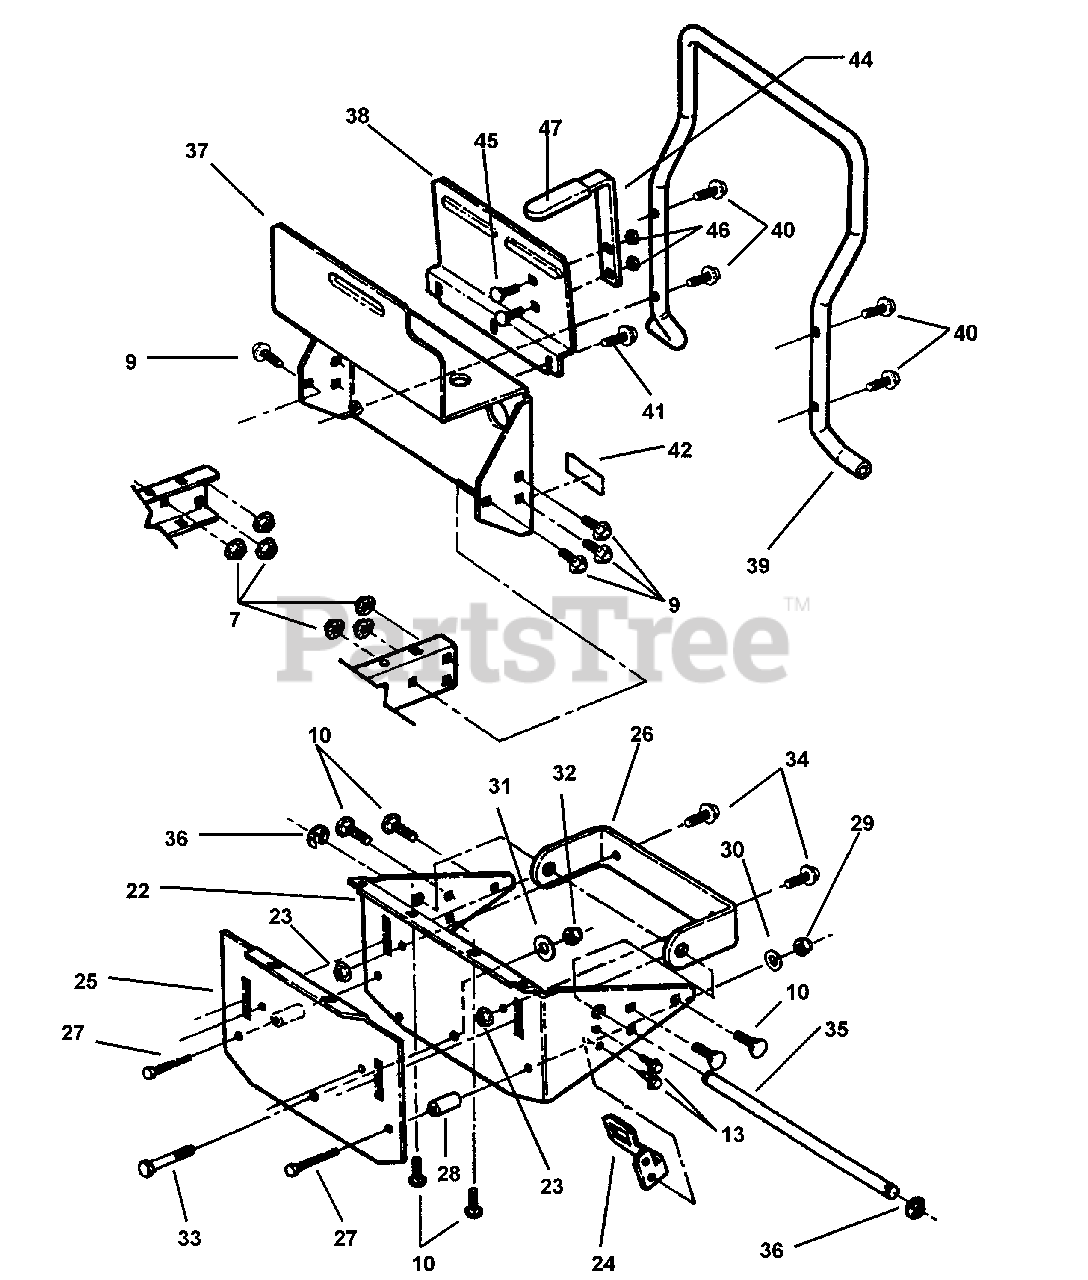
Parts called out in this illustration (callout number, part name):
7	NUT, 5/16-18 Hex Flange Lock, Grade 5
9	BOLT, 5/16-18 x 5/8" Hex Flange Lock, Grade 5
10	BOLT, 5/16-18 x 3/4" Short Neck Carriage, Grade 5
13	SCREW, 1/4-20 x 3/8" Hex Washer Self-Tap
22	ATTACHMENT PLATE, Front Frame
23	NUT, 3/8-16 Hex Flange Lock
24	BRACKET, Switch
25	ATTACHMENT PLATE, Front Axle
26	BRACKET, Attachments
27	SCREW, 3/8-16 x 2-3/4" Hex Head Cap, Grade 5
28	SPACER, .19 I.D. x .5 O.D. x 1.8 Long
29	NUT, 3/8-16 Hex Nyloc
30	WASHER, 3/8" SAE Flat
31	WASHER, 1/2" SAE Flat
32	NUT, 1/2-13 Hex Nyloc
33	SCREW, 1/2-13 x 3" Hex Head Cap, Grade 5
34	BOLT, 3/8-16 x 3/4" Hex Flange Lock
35	SHAFT, Forward/Reverse/Brake Pedals
36	RING, External Retaining (5/8" Shaft)
37	ATTACHMENT PLATE, Rear Frame
38	BRACKET, Fuel Tank
39	BUMPER, Rear
40	SCREW, 5/16-18 x 1-3/4" Hex Washer Self-Tap
41	SCREW, 5/16-18 x 5/8" Hex Washer Self-Tap
42	DECAL, Roll Release
44	BRACKET, Fuel Tank
45	BOLT, 1/4-20 x 5/8" Flat Head Square Neck, Grade 2
46	NUT, 1/4-20 Hex Flange Lock, Grade 5
47	COVER, Vinyl
